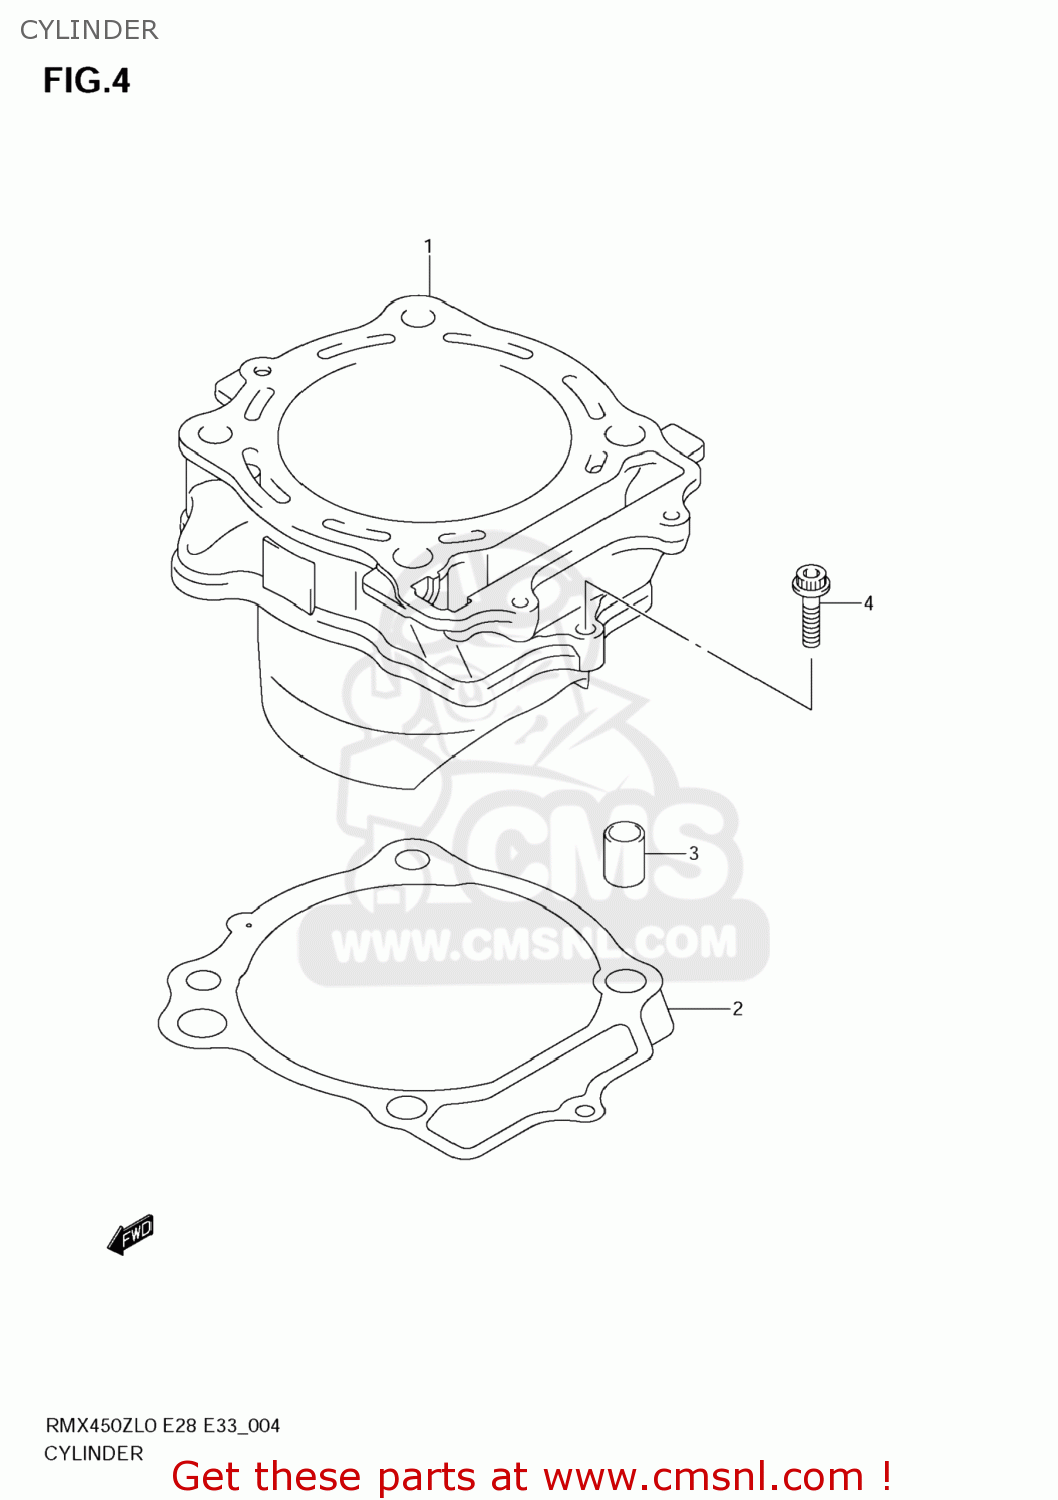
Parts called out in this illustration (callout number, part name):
1	CYLINDER
2	GASKET,CYLINDER (NAS)
3	PIN
4	BOLT
